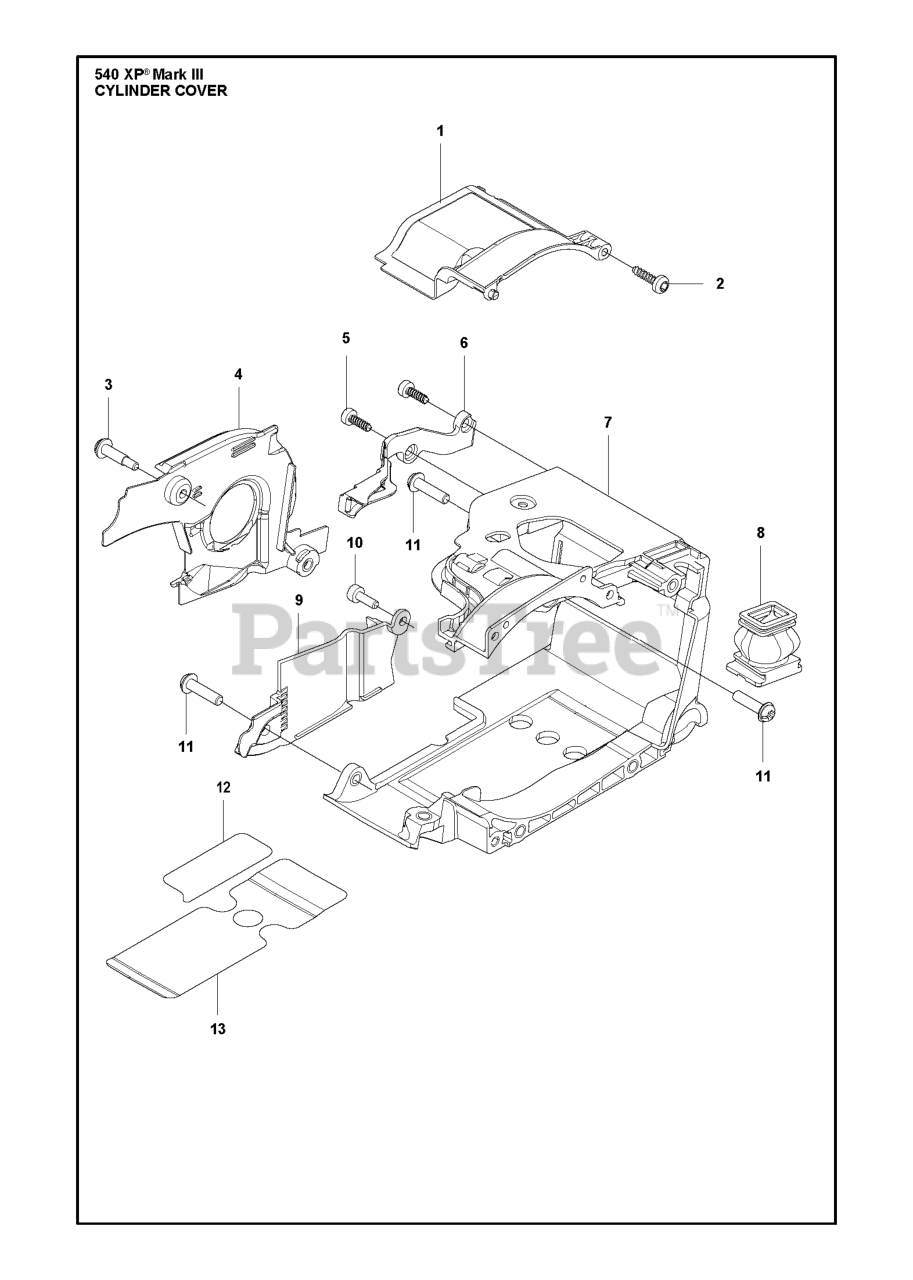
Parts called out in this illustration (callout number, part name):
5	SCREW
10	BOLT M4 X 12 T27
11	SCREW HEXABOULAR SLOTTED SOCKE
